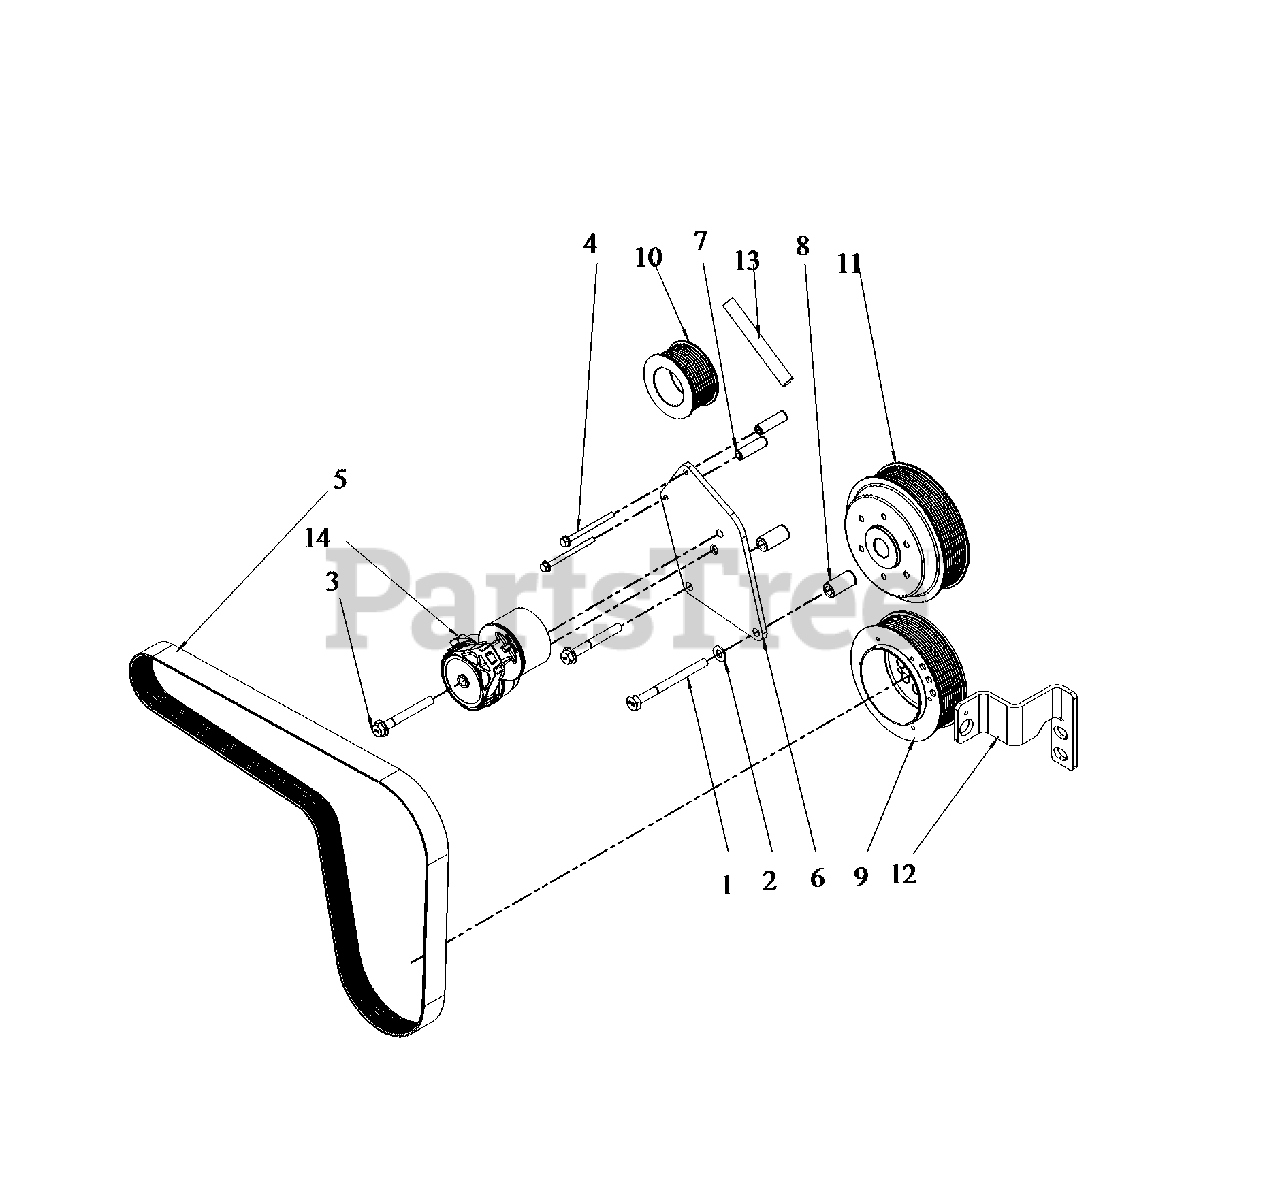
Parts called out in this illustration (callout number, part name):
1	* BOLT
2	* WASHER, FLAT
3	* BOLT, FLANGE
4	* BOLT, FLANGE
5	BELT, DRIVE
6	* MOUNT, TENSIONER
7	* SPACER, TENSIONER MOUNT
8	* SPACER, TENSIONER MOUNT
9	PULLEY, CRANK
10	PULLEY, ALTERNATOR
11	PULLEY, FAN
12	* BRACKET, CRANK SENSOR
13	* SLEEVE, ALTERNATOR SPACER
14	* TENSIONER, PULLEY
